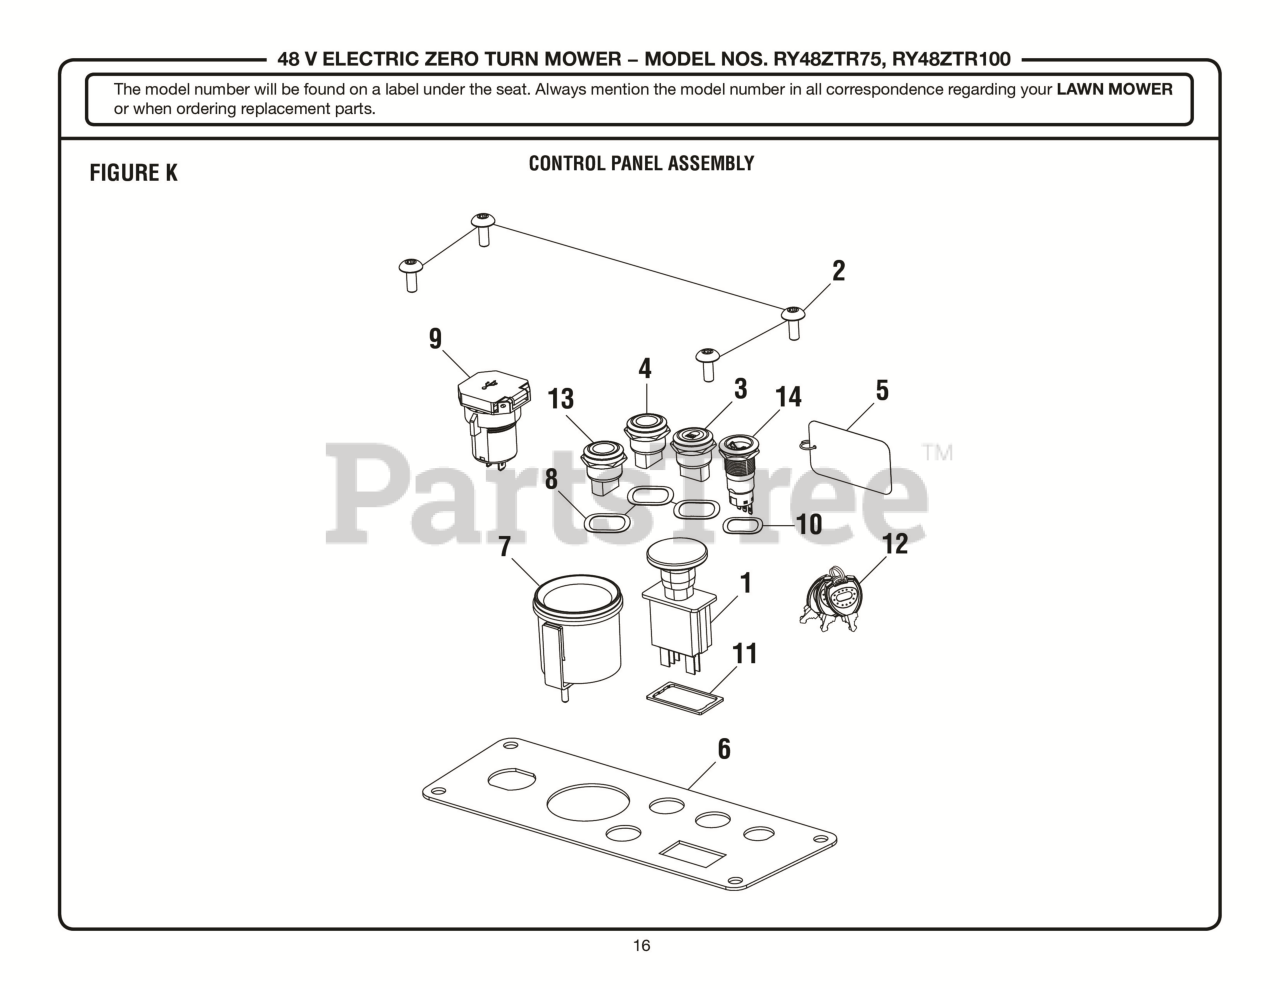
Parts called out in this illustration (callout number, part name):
1	Power Take Off Button (PTO)
2	Screw (M6 x 10 mm, Soc. Button Hd.)
3	Light Switch
4	Button Switch, Drive Speed
5	Watch For Kids, Keychain Label
6	Control Panel Face Plate
7	Fuel Gauge, ZTR
8	Wavy Washer
9	USB Module
10	Wavy Washer
11	PTO Gasket
13	Button Switch, Blade Speed
14	Switch Key Module
